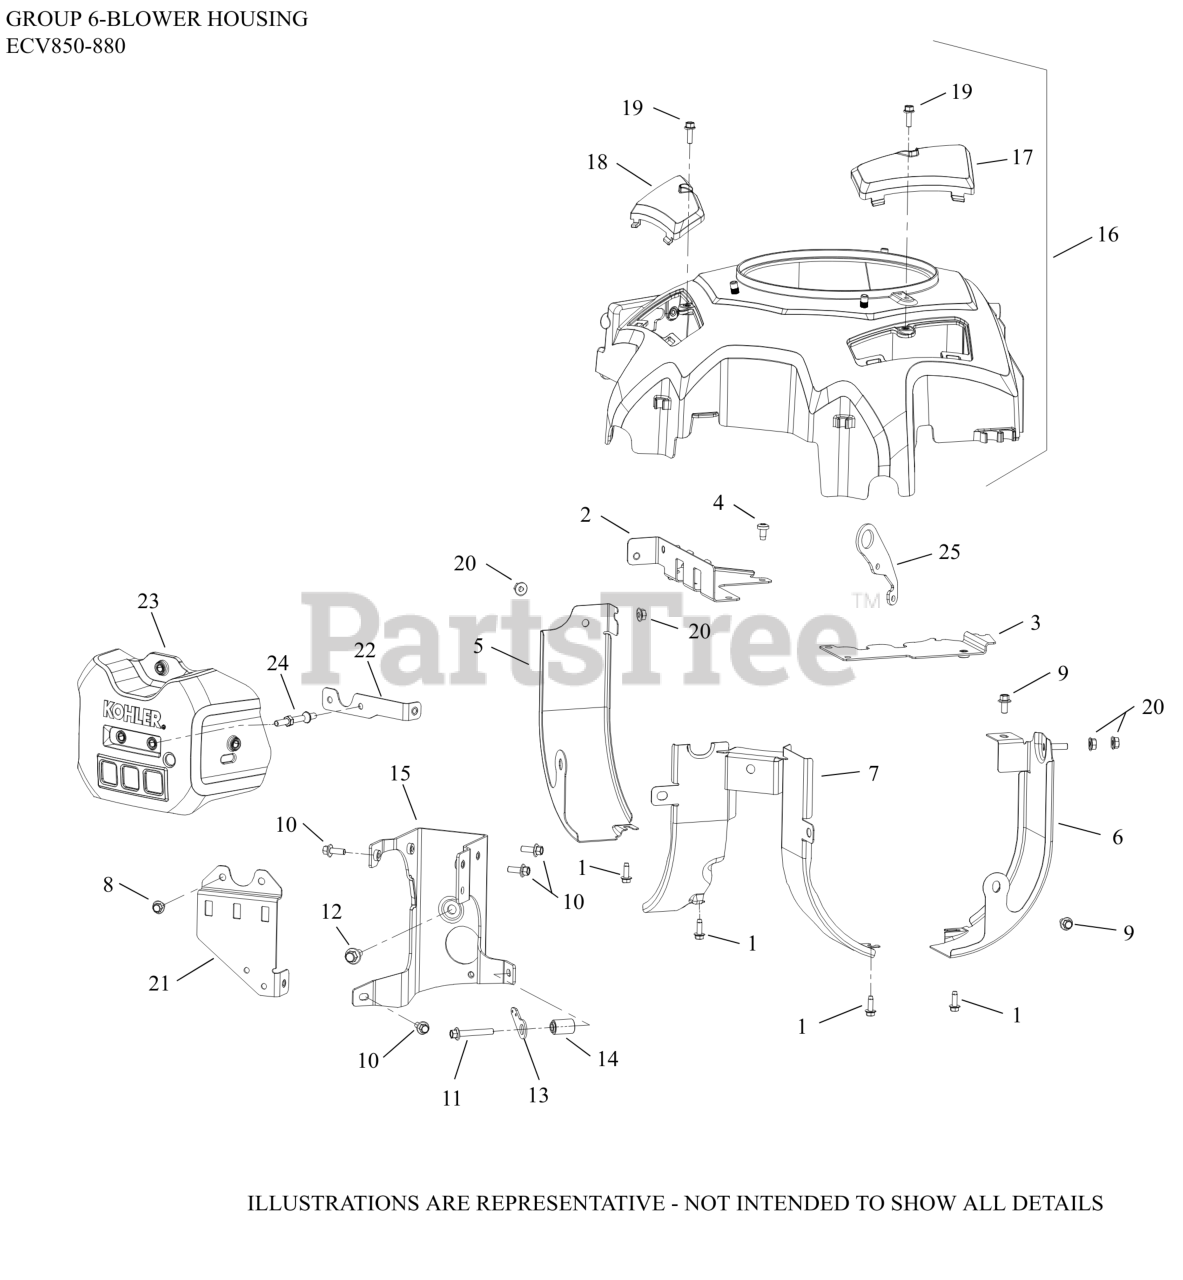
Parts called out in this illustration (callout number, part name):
1	SCREW, THREAD FORMING
1	SCREW,THREAD FORMING
2	BAFFLE, CRANKCASE #1 CYLINDER
3	BAFFLE, CRANKCASE #2 CYLINDER
5	BAFFLE, BARREL #1 CYLINDER
6	BAFFLE, BARREL #2 CYLINDER
7	BAFFLE, VALLEY ASSEMBLY
8	SCREW, FLG M6X1.0X10
9	SCREW, FLG M6X1.0X12
10	SCREW, FLG M6X1.0X16
11	SCREW, FLG M6X1.0X40
12	SCREW, FLG 8X1.25X16
13	LEVER, GOVERNOR LINKAGE
14	SPACER, STEPPED O.D.
15	BRACKET, THROTTLE BODY
16	KIT, BLOWER HOUSING
17	COVER, CLEAN OUT #2 CYLINDER
18	COVER, CLEAN OUT #1 CYLINDER
19	SCREW, HVY FLG M5X.8X16
21	BRACKET, FUSE HOLDER
22	BRACKET, FUSE COVER
23	COVER, FUSE
24	STUD, BLOWER HOUSING MOUNTING
24	LEVER, GOVERNOR LINKAGE
